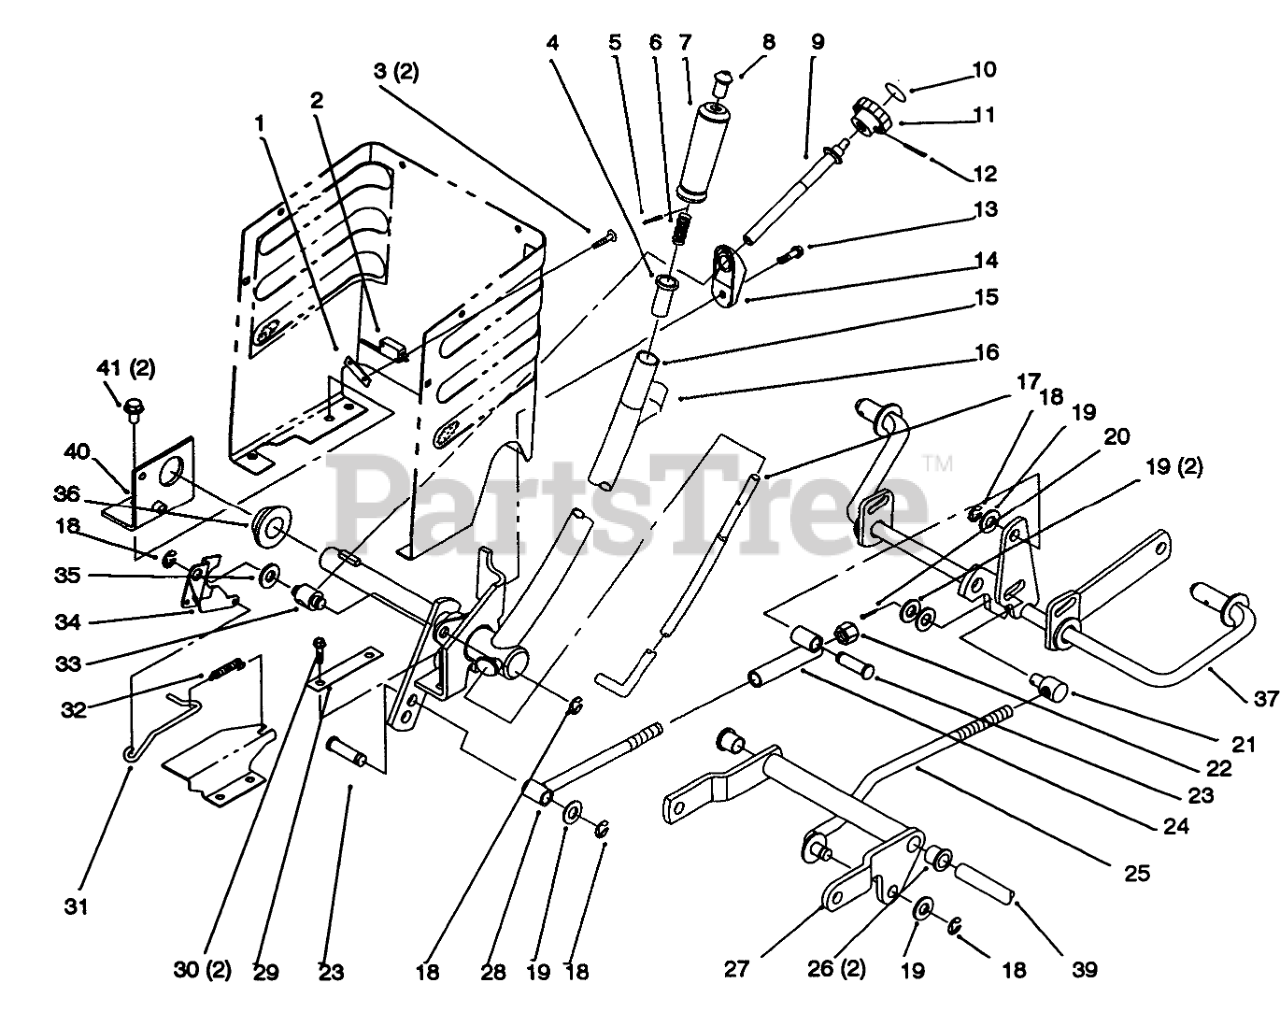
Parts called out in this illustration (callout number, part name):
1	NUT-SPEED
2	SWITCH-MICRO
3	SCREW-HH
4	RETAINER-SPRING
5	PIN-SPIROL
6	SPRING-COMPRESSION
7	GRIP-HANDLE
8	TIP-ROD
9	ROD - HOC
10	DECAL-HEIGHT KNOB
12	PIN-SPIROL
13	SCREW-HWH
14	WEDGE - HOC
15	Lever-Lift
16	Decal-Lift (Only On: 72042, 72043, 72083)
16	Decal-Lift (Only On: 72103, 72063, 72062)
17	ROD-LEVER, LIFT
18	RING-RETAINING, EXTERNAL
19	WASHER-FLAT
20	PIN-COTTER
21	ROD-TRUNNION LIFT
22	NUT-LOCK, NI
26	BUSHING-FLANGE
27	ARM-PIVOT
30	SCREW-HWHTF
31	ROD - HOC INDICATOR
32	SPRING - EXTENSION
33	TRUNNION
34	PLATE - HOC GAGE
35	WASHER
36	BEARING-FLANGE
37	SHAFT-GAGE
39	Shaft
40	PIVOT LINKAGE WABLK
41	Screw-HH (Only On: 72043, 72103, 72063, 72083)
41	Screw-TAP (Only On: 72042, 72062)
